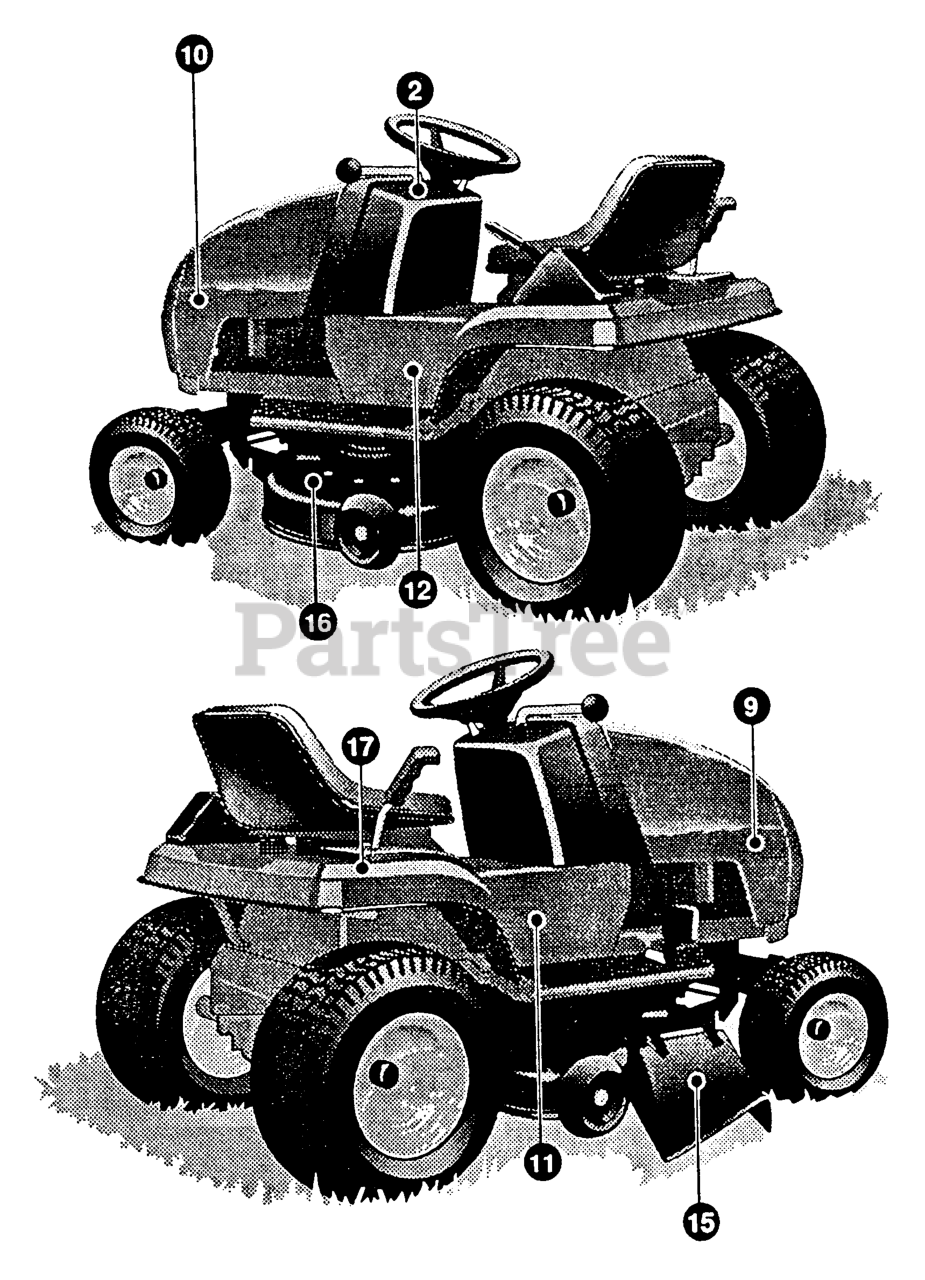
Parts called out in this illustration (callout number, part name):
9	HOOD, 14.5 HP
10	HOOD, 14 5 HP
11	43" CONSOLE (RH)
12	43" CONSOLE (LH)
15	MULCH KIT INST
16	MOWER DECK
17	AUTO TRAN
